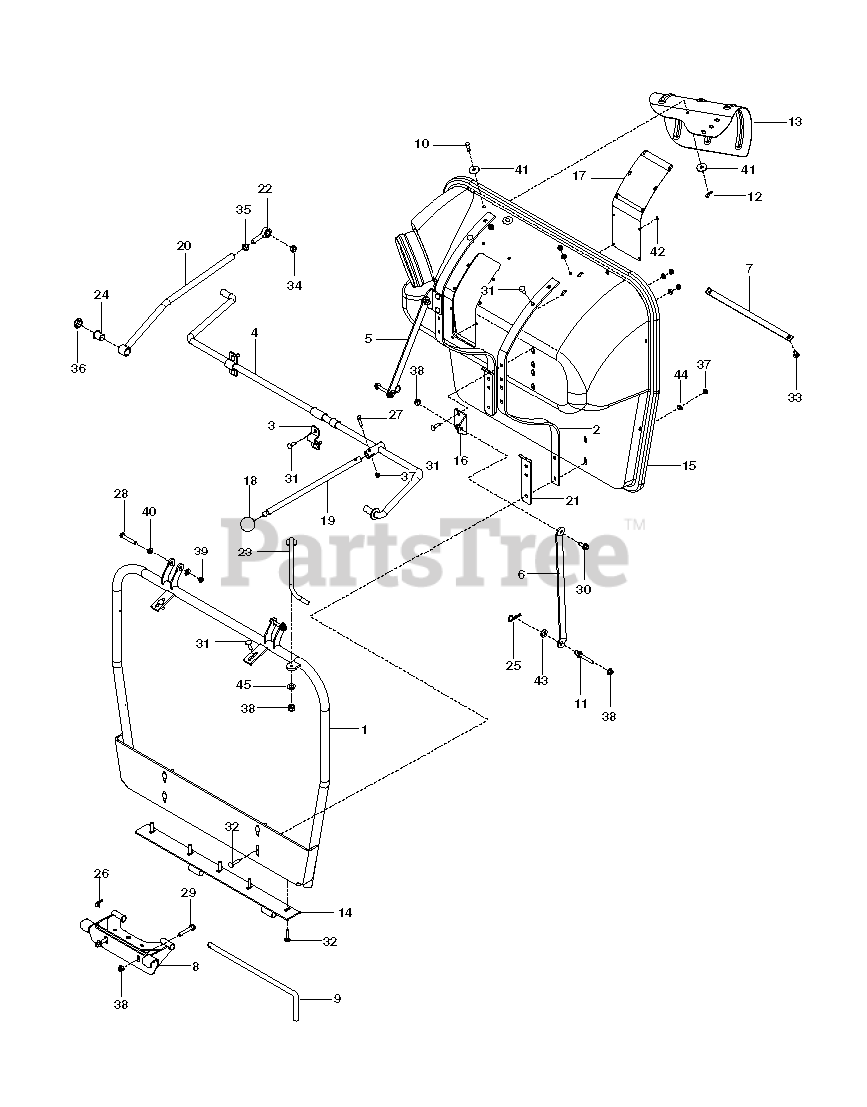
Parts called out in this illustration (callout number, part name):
1	FRONT FRAME WLDT.
4	LIFT.SHAFT.WELDMENT(LIKE117986
5	STRAP.MTG.LH.BLK
6	STRAP.MTG.RH.BLK
10	CLEVIS PIN 5/16
11	PIN, MOUNT
12	RETAINER SPRING
14	MOUNT.LOWER.CLAMSHELL
15	CLAMSHELL.FRT.PLASTIC.
16	BRKT.MTG.BLK
18	KNOB.2".BALL.BLK.5/8-18"THREAD
20	LINKAGE.LATCH
21	CLAMSHELL SUPPORT PLATE
23	LINKAGE.LATCH
25	HAIRPIN #4
26	PIN, COTTER 1 3/4
27	CAPSCREW 5/16 X 1/1/2 HEX HEAD
28	HCS 3/8C X 2 1/4
29	HHFS 3/8-16 X 2.25 GD 8
30	HHFS 3/8-16 X 1 GRD 5 ZD
31	BOLT, CARRIAGE 5/16X1-1/4
32	RHSNB 5/16-18 X 1-1/2 GR 5 ZD
33	BOLT 5/16C X 3/4" CARRIAGE
34	NUT 1/2-13 HEX JM NYL
35	SPINDLE
36	NUT, 3/4-16 HEX THIN NYLOC ZD
37	NUT 5/16 NYLOC
38	NUT 3/8-16 HEX FLG NYLOC ZD
39	NUT HEX 3/8-16 NYLON, THIN
40	WASHER 3/8 SAE FLAT
41	WASHER, FENDER 5/16
42	WASHER, #10 MACH SCR BLK OX
43	WASHER 1/2" FLAT
44	WASHER 5/16 FLAT
45	FLAT WASHER 5/16 SAE
